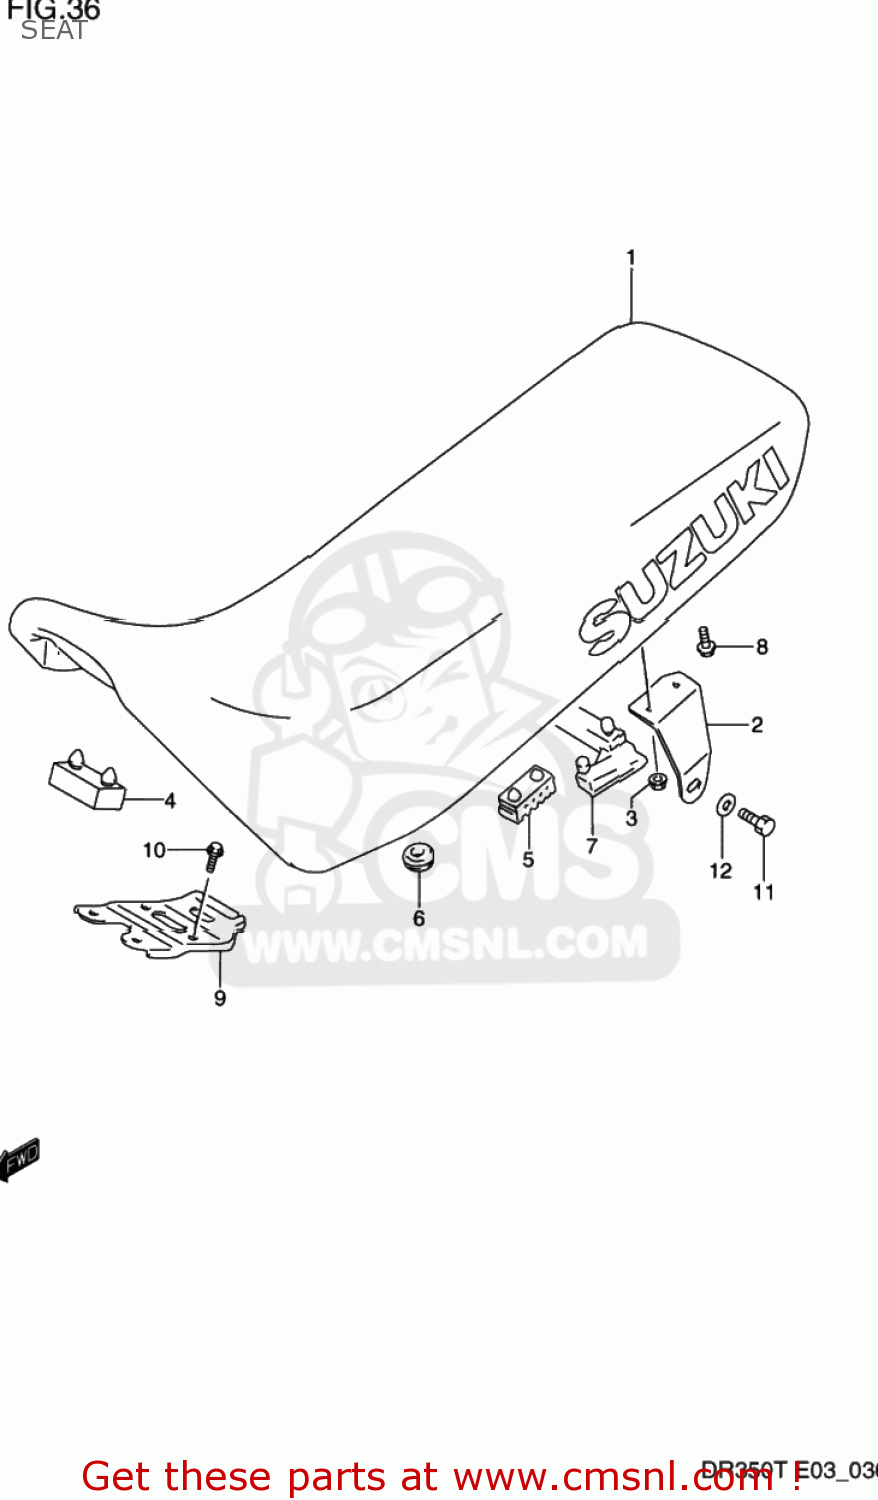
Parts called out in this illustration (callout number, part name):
1	SEAT SET
2	BRACKET,SEAT,R
3	NUT
4	CUSHION
5	CUSHION,SEAT(40X20X15)
6	CUSHION
7	CUSHION
8	BOLT
9	PLATE,SEAT FR HOOK
10	BOLT
11	BOLT
12	WASHER
